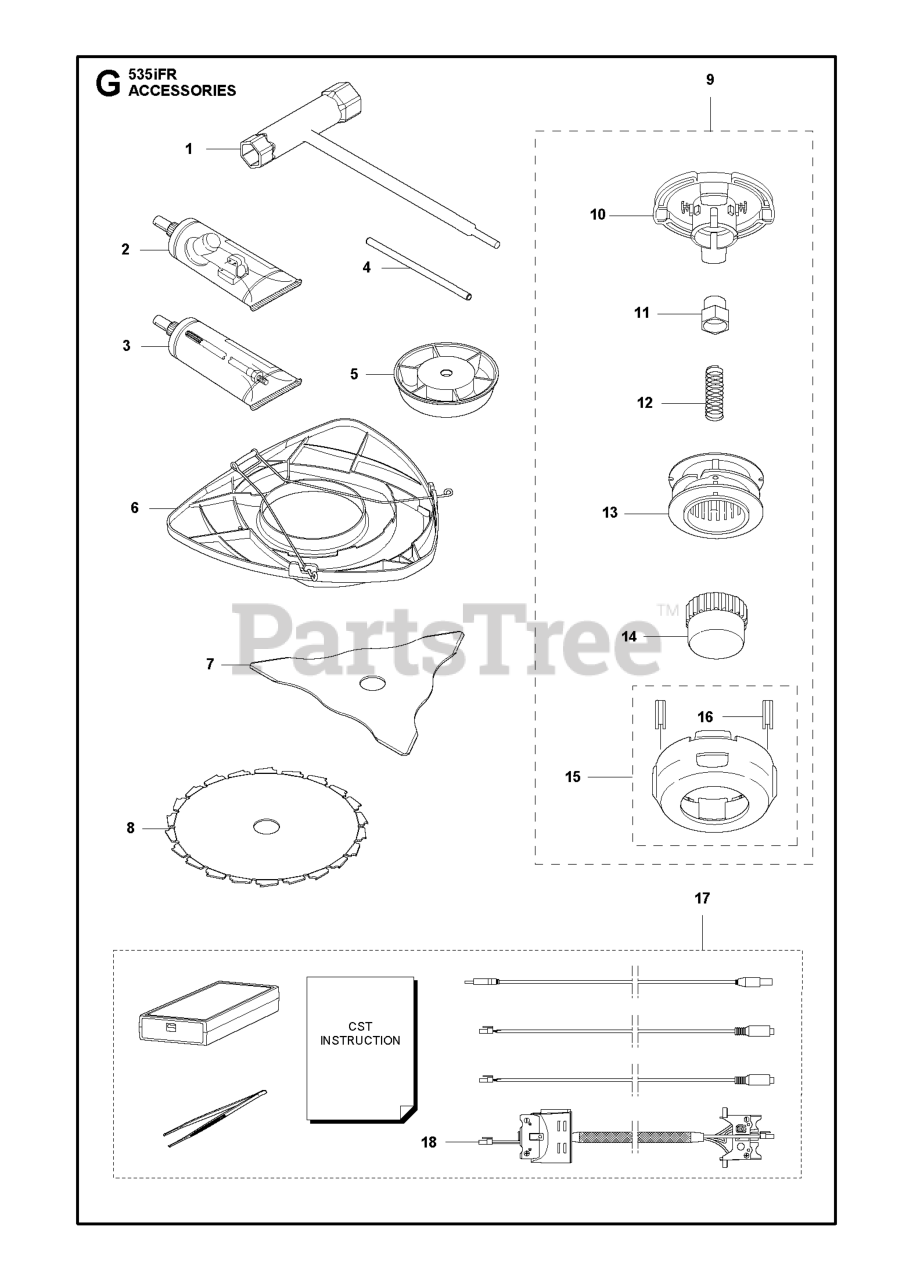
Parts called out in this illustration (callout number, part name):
1	COMBINATION WRENCH TORX
2	BEVEL GEAR GREASE
3	DRIVE SHAFT GREASE (200 G)
4	LOCKING PIN
5	SUPPORT CUP
6	TRANSPORT GUARD
8	RPHUS 8"SCARL BLADE 200-22T 1"
9	TRIMMER HEAD T35 M12L
15	TRIMMER HEAD HOUSING
17	DIAGNOSTIC TOOL KIT
18	WIRING ASSY
